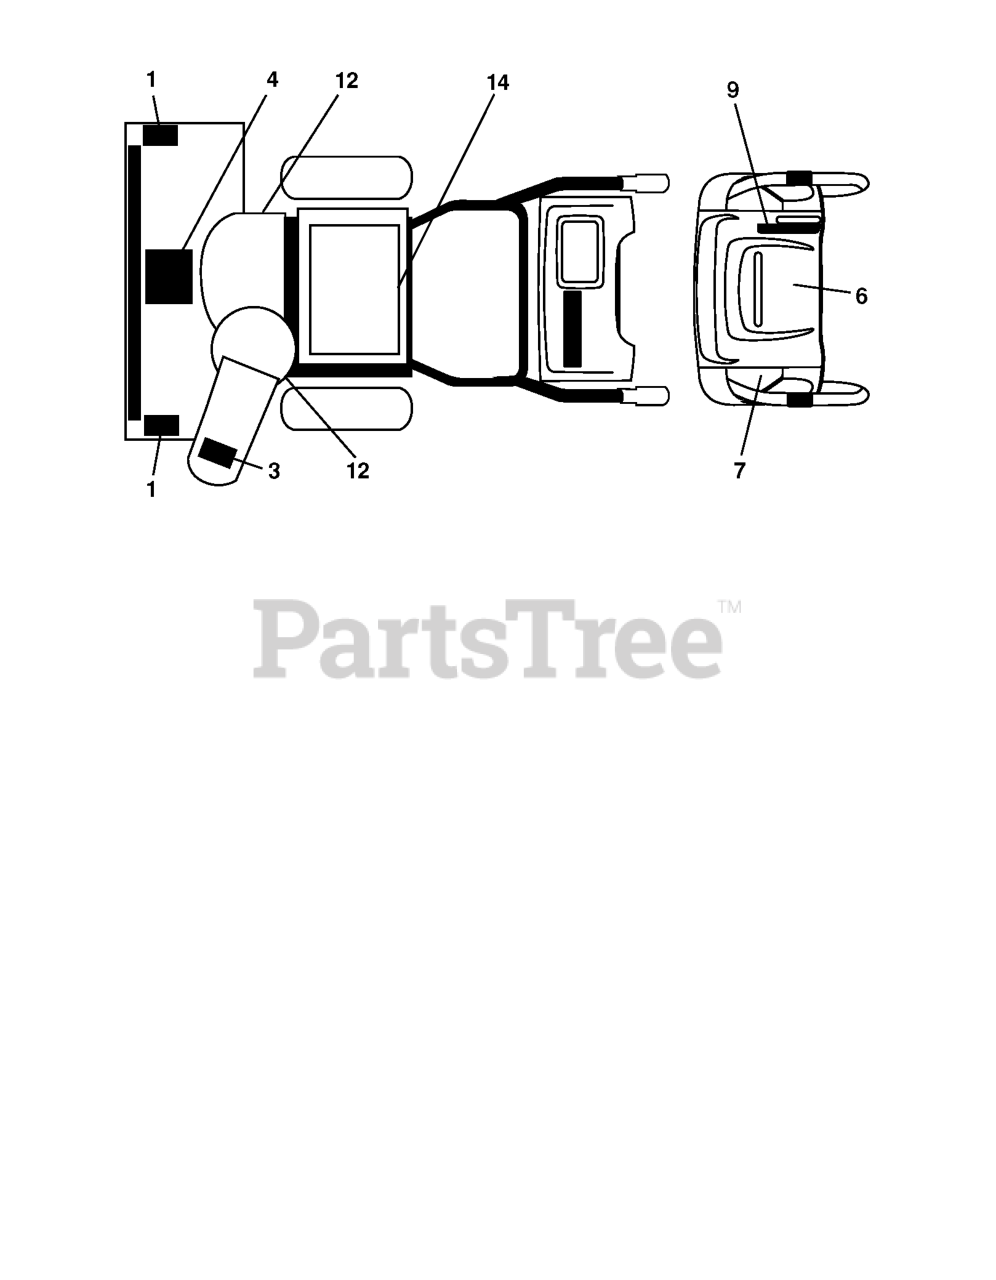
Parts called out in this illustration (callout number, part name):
1	DECAL.AUGER.SAFETY.
3	DECAL.CHUTE.SAFETY.
4	DECAL.AUGER."
7	DECAL.CONS.LT.SPD/LEV/PWRST.
9	DECAL.CONS.RT.SPD/LEV/PWRST.
12	DECAL.BELT.GUARD.
14	DECAL.FENDER
